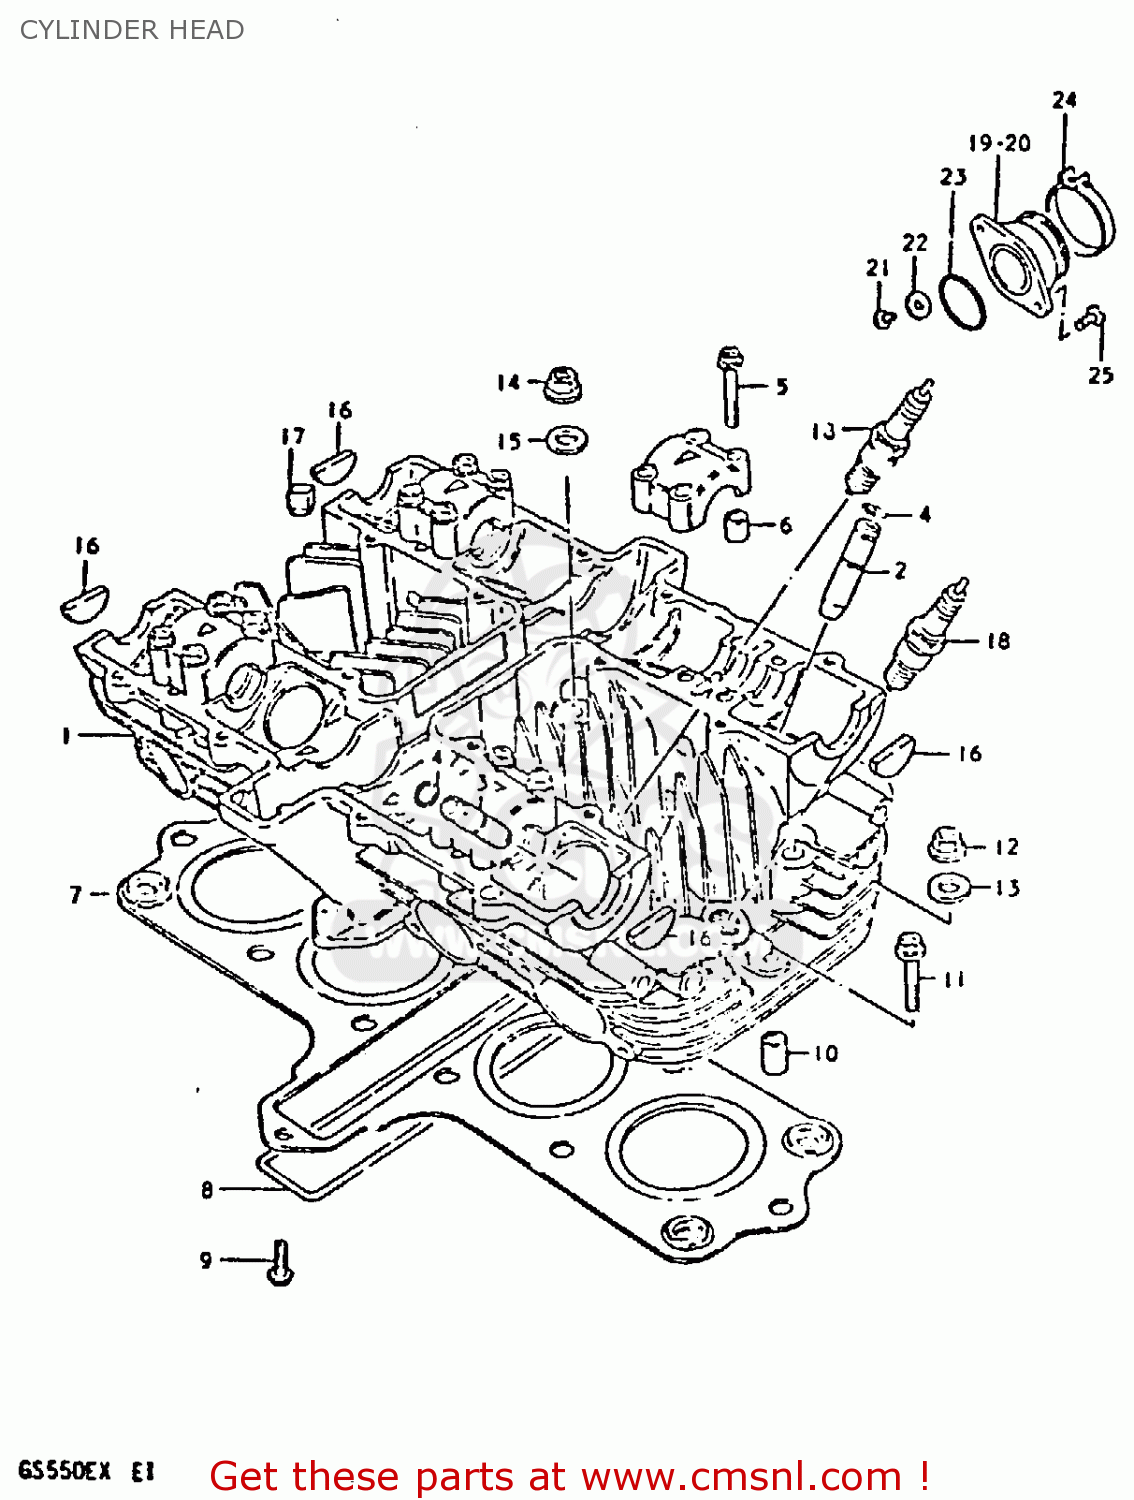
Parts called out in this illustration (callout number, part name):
1	HEAD ASSEMBLY,CYLINDER
2	GUIDE,INTAKE VALVE
3	GUIDE,EXHAUST VALVE
4	RING,SNAP
5	BOLT(6X39)
6	PIN(6.2X8X11)
7	GASKET,CYLINDER HEAD (MCA)
8	O RING(D:3,ID:26X157)
9	BOLT
10	PIN
11	BOLT,UNDER
12	NUT
13	GASKET (NAS)
14	NUT
15	WASHER(8.5X19X2.3)
16	PLUG
17	PAD
18	SPARK PLUG
19	PIPE,INTAKE,R
20	PIPE,INTAKE,L
21	BOLT
22	WASHER
23	O-RING
24	CLAMP
25	SCREW
